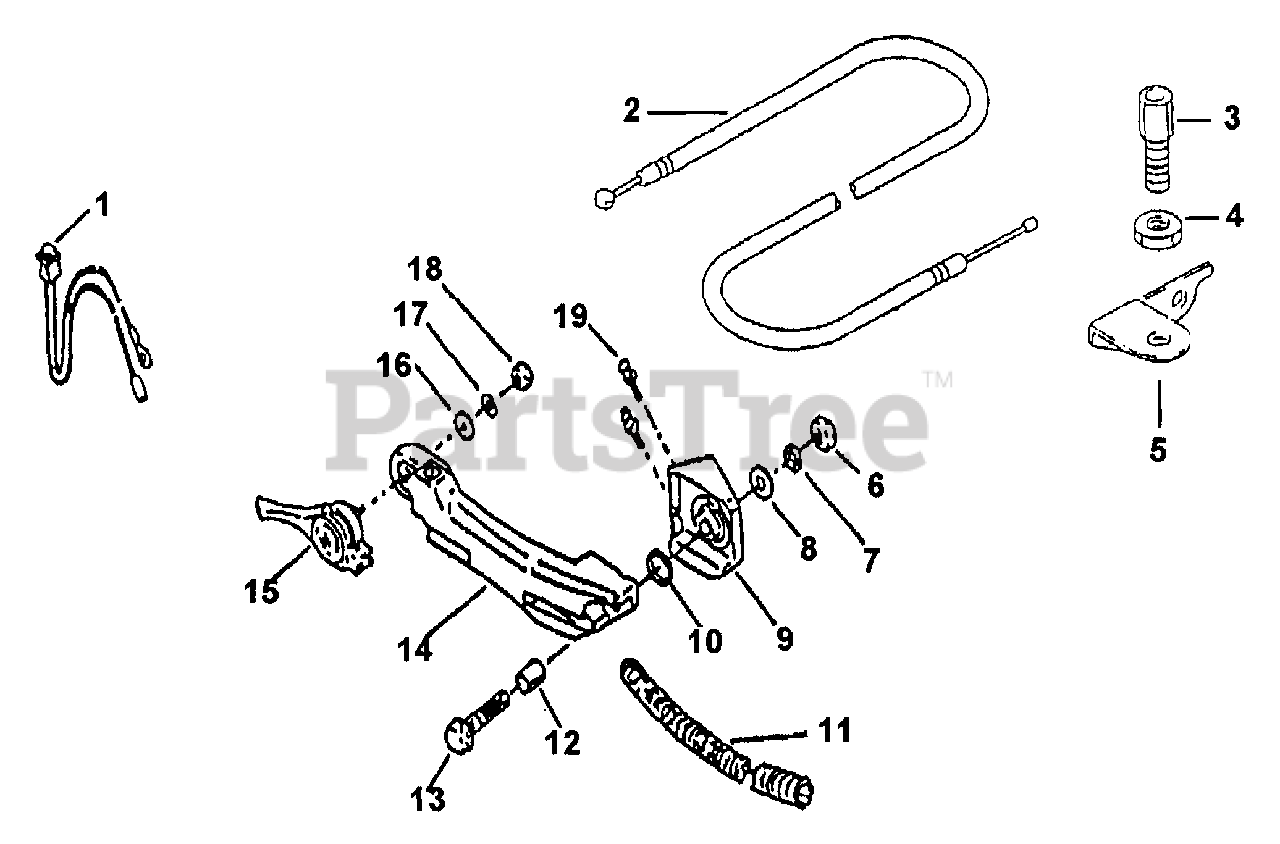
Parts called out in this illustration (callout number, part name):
1	STOP SWITCH
2	THROTTLE CABLE
3	CABLE ADJUSTER
4	NUT
6	NUT
7	LOCK WASHER
8	FLAT WASHER
13	BOLT
15	THROTTLE LEVER
16	FLAT WASHER
17	LOCK WASHER
18	NUT
19	SCREW
